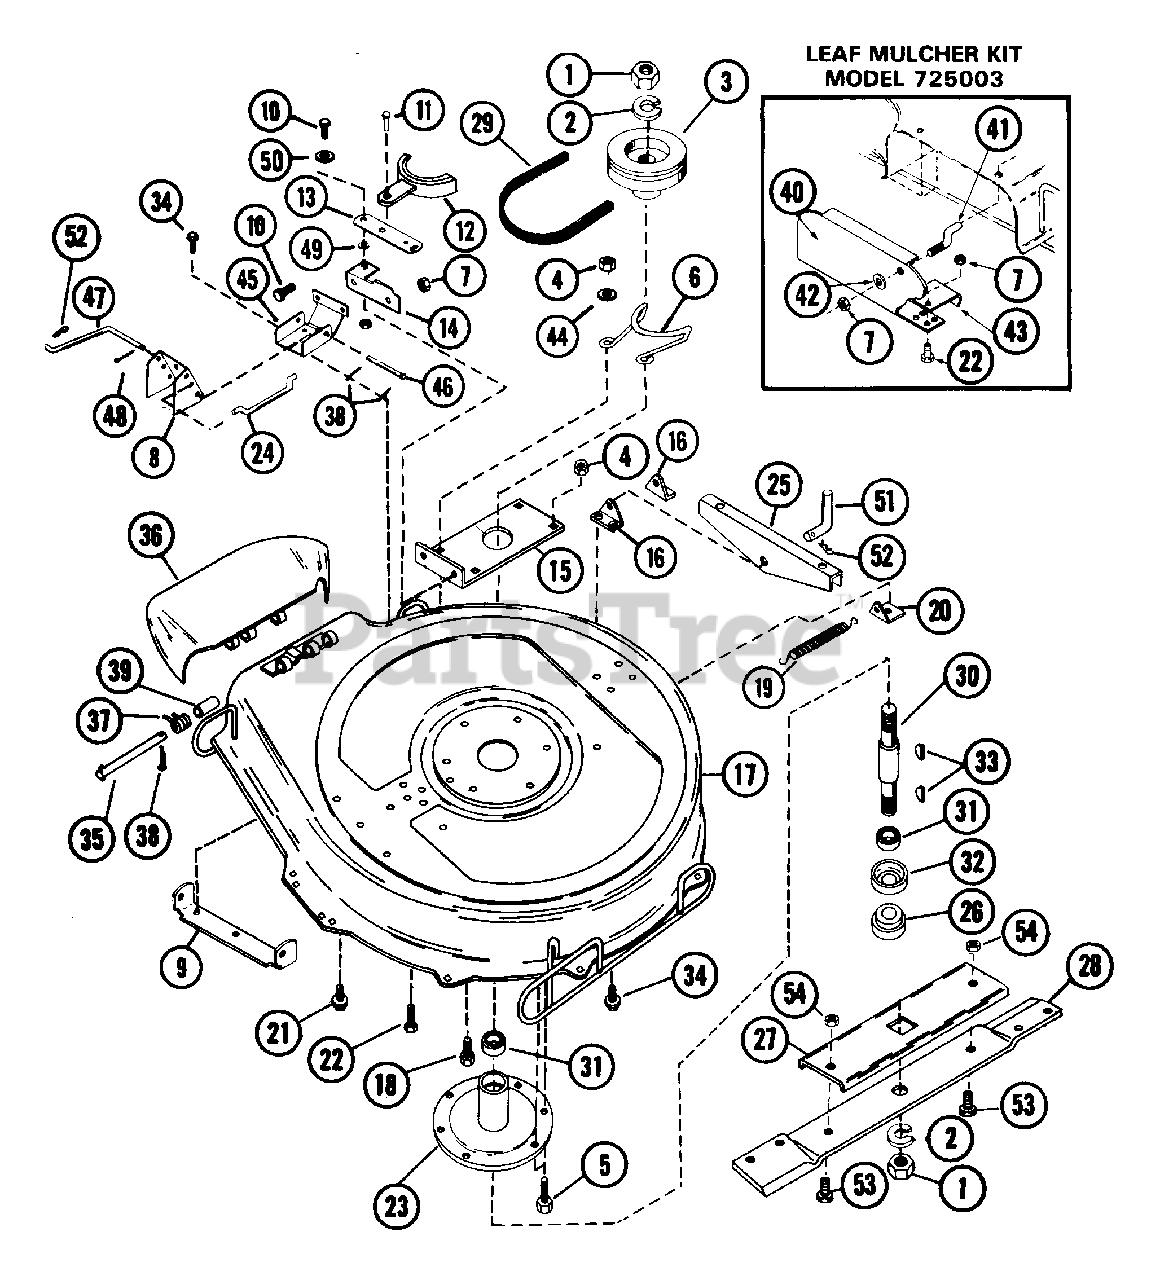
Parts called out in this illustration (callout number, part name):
1	NUT-JAM .75-10 PL
2	WSHR-LK .750X.188 MED PL
3	MOWER SHEAVE
4	NUT-LK-CTR .375-16 GR A PL
5	BLT-HEX .38-16X1.00 PL
6	MOWER BELT FINGER
7	NUT-LK .312-18 GR A PL
8	MOWER ENGAGING ARM
9	FRONT MOUNTING BRACKET
10	BLT-HEX .31-18X.63 PL GR 2
11	RVT .25X.50 RH ST
12	BLADE BRAKE
13	MOWER BRAKE LEVER
14	BRAKE BRACKET
16	REAR MOUNTING BRACKET
17	30"MOWER PAN W/DEFLECTOR&DECAL
18	BLT-SERHFWH .25-20X.50 PL
19	SG-TENS .072X.51X5.31 WLD 25
20	BRAKE CLIP
21	BLT-SCRHFWH .38-16X.50 PL
22	BLT-HEX .31-18X.50 PL GR2
23	SPINDLE HOUSING
24	MOWER BRAKE LINK
25	SWIVEL BRACKET
26	RETAINER HUB
27	BLADE TRAY
28	MOWER BLADE 30 INCHES
29	V-BELT
30	SPINDLE SHAFT
31	BRG-BALL .750X1.781X.61
32	BEARING SLINGER
33	KEY-WDRF .188X.75X.313 SAE 9
34	BLT-SERHFWH .31-18X.50 PL
35	CLEVIS PIN
36	PAN CHUTE EXTENSION
37	SG-TORS .095X.50X 1.0
38	PIN-COTR .09X.75 PL
39	BSHG-SLV .334 X .502 X 1.437
40	LEAF MULCHER KIT-EMPEROR
42	WSHR-FL-STL .38X.875X.083 PL
43	MULCHER BRACKET
44	WSHR-FL-STL .406X.865X.094 PL
45	PIVOT BRACKET
46	PIN-CLEV .309X3.50 SP
47	MOWER ENGAGEMENT LINK
48	PIN-COTR .12X.75 PL
49	SPACER
50	WSHR-FL-STL .328X1.0X.094
51	CLEVIS PIN
52	PIN-HAIR INT .08X.38X1.42 YWZC
53	BLT-HEX .38-16X.75 PL GR5
54	NUT-LK TOP .375-16 GR C YWZC
